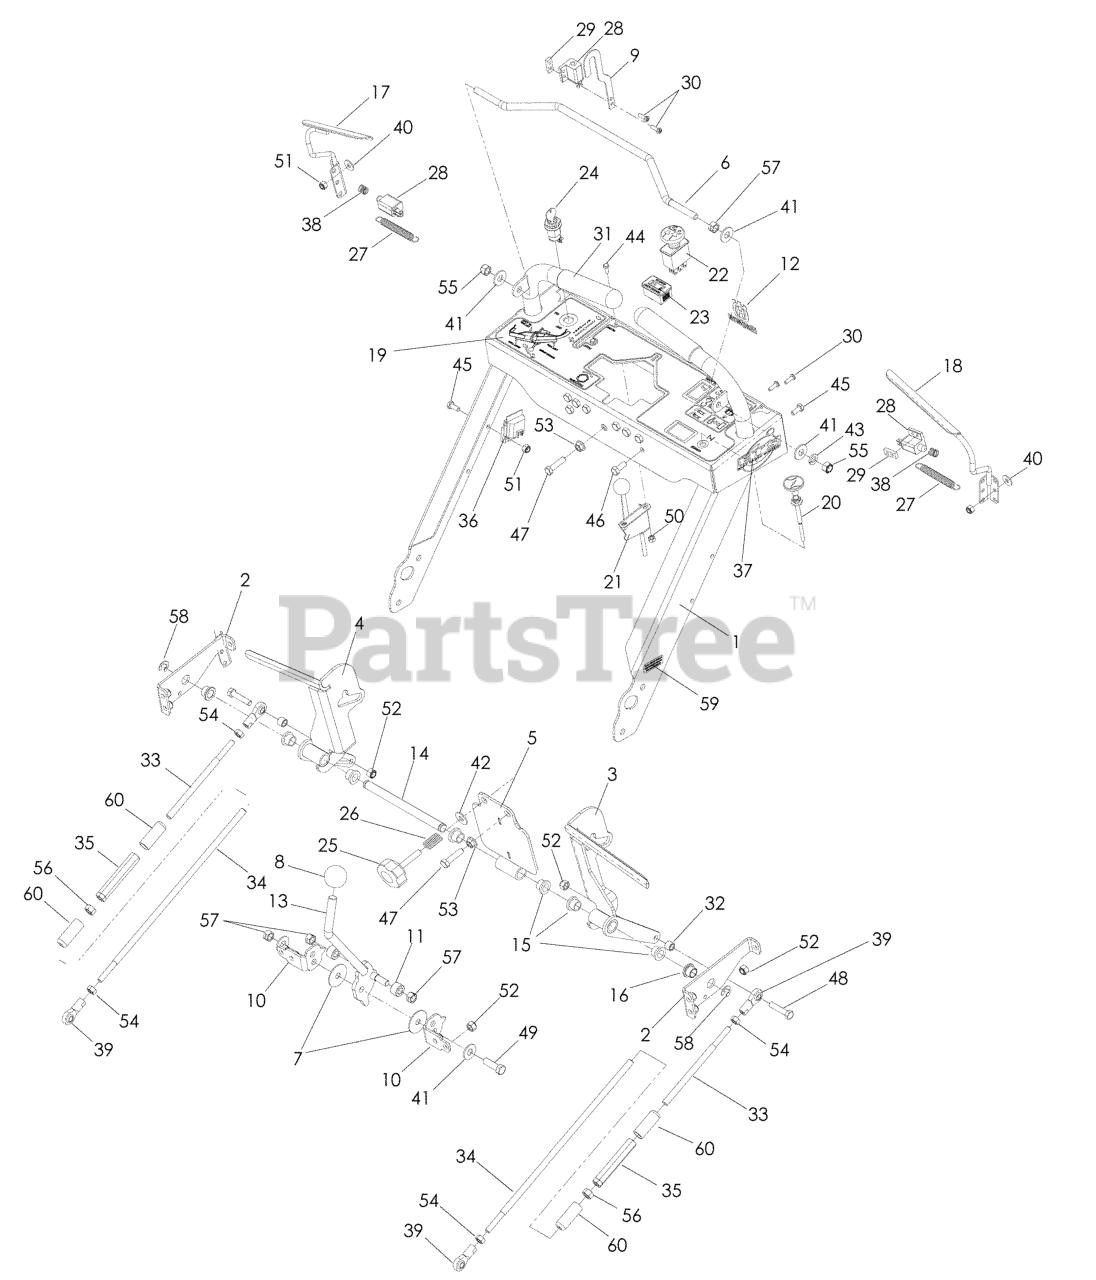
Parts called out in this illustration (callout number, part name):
1	HANDLE W/ DECALS
3	DRIVE LEVER LT
4	DRIVE LEVER RT
5	TRACKING PLATE
7	WASHER, FRICTION
9	NEUTRAL ARM
10	FRICTION PLATE
12	DECAL CROWN H 2-1/4 BLUE
13	GROUND SPEED LEVER
14	CROSS SHAFT
15	BUSHING, FLANGED NYLON
16	FLANGE BUSHING
19	DECAL, CONSOLE
20	CONTROL-CHOKE 51"
21	THROTTLE CONTROL W/BALL KNOB
22	RP.SWITCH, BLADE
23	DNO HOUR METER
24	KEY SWITCH, COMPLETE
25	ADJUSTMENT KNOB
29	TAPPED PLATE
30	SCREW #10-24 X 5/8
33	SHORT LINKAGE
34	LINKAGE, LOWER
35	TURNBUCKLE, 3/8
37	DECAL, ETS
38	SPRING, SWITCH
39	BALL JOINT, RIGHT HANDED
40	WASHER 1/4 FLAT
41	WASHER 3/8 FLAT
42	WASHER 5/16 FLAT
43	SLW 3/8 STD
44	HCS #10-24 X 1/2
45	HCS 1/4C X 5/8
46	HCS 5/16C X 3/4
47	BOLT, TAP 5/16-18
48	CAPSCREW 5/16 X 1/1/2 HEX HEAD
49	HCS 3/8C X 1 1/4 GR5
50	NUT 10-24 NYLOC
51	NUT.1/4-20.HEX.NYLOC.ZD
52	NUT 5/16 NYLOC
53	NUT 5/16C WHIZ
55	NUT 3/8-16 NYLOC
57	NUT 3/8C CENTERBLOCK
58	E-RING 1/2 (2 2)
59	DECAL, DUAL HEIGHT
